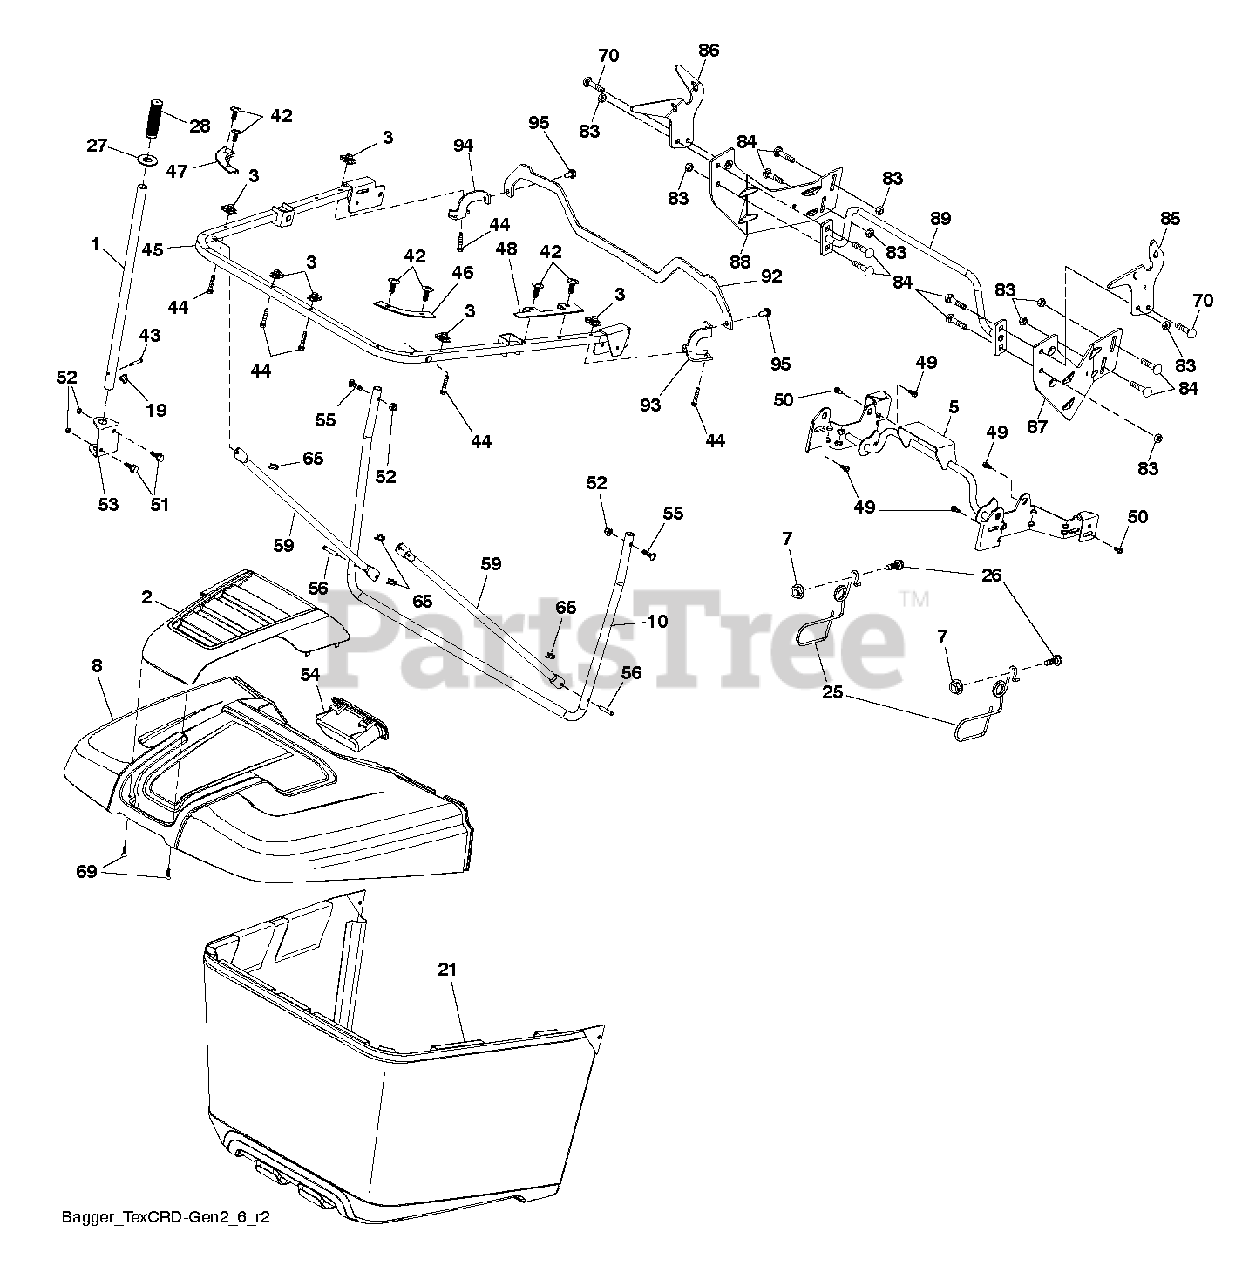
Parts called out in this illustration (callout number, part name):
1	TUBE.HANDLE.BAGGER.CRD/SRD.BLA
2	APPLIQUE.BAGGER
3	1/4-20 U NUT
5	FRAME TEX_CRD_GEN2 UPPER PIVOT
7	NUT T
8	BAGGER TOP
10	FRAME TEX_CRD_GEN2 BAGGER FRAM
19	PIN.COTTER.5/16.BOW TI
21	BAGGER.ASM.FABRIC.CRD.GII.HUSQ
25	LATCH LATCH. BAG. CRD GEN 2
26	SCREW HEX CRT
27	GROMMET RUBBER GROMMET, DUMP T
28	GRIP.HANDLE.BLACK
42	CLIP CHRISTMAS TREE CLIP
43	RIVET,DRILLED
45	FRAME TEX_CRD_GEN2 UPPER U FRA
46	CONNECTOR RIGHT BAGGER CORNER
47	CONNECTOR LEFT BAGGER CORNER C
48	BAFFLE BAGGER SIDE CLOSE-OUT
49	BOLT, SHOULDER 5/16-18
50	BOLT, 5/16-18 X 1 3/4
51	BOLT.CARR.SQNK.5/16-18UNC.X3/4
52	NUT.71038.31-18.HEX.NYLOCK
53	BRACKET DUMP HANDLE BRACKET, T
54	HANDLE BAGGER TOP FRONT HANDLE
55	BOLT
56	PIN.CLEVIS.183
59	TUBE BAGGER SPREADER TUBE, TEX
65	RETAINER M
69	SCREW,#8.FLAT.HEAD.DRILL.TIP
70	SCREW, 3/8-16X3/4
83	NUT
84	BOLT D
85	BRACKET.RH.PIVOT.MAN.DUMP.BLAC
86	BRACKET.LH.PIVOT.MAN.DUMP.BLAC
87	BRACKET.RH.MID.SUP.BAG.TEX.CRD
88	BRACKET.LH.MID.SUP.BAG.TEX.CRD
89	TUBE.WELD.OFSET.STRUT.BAG.X431
92	BRACKET.PNT.BAGGER.TOP.SUPPORT
93	BRACKET.PNT.RH.SUPPORT.ATTACH
94	BRACKET.PNT.LH.SUPPORT.ATTACH
95	SCREW
